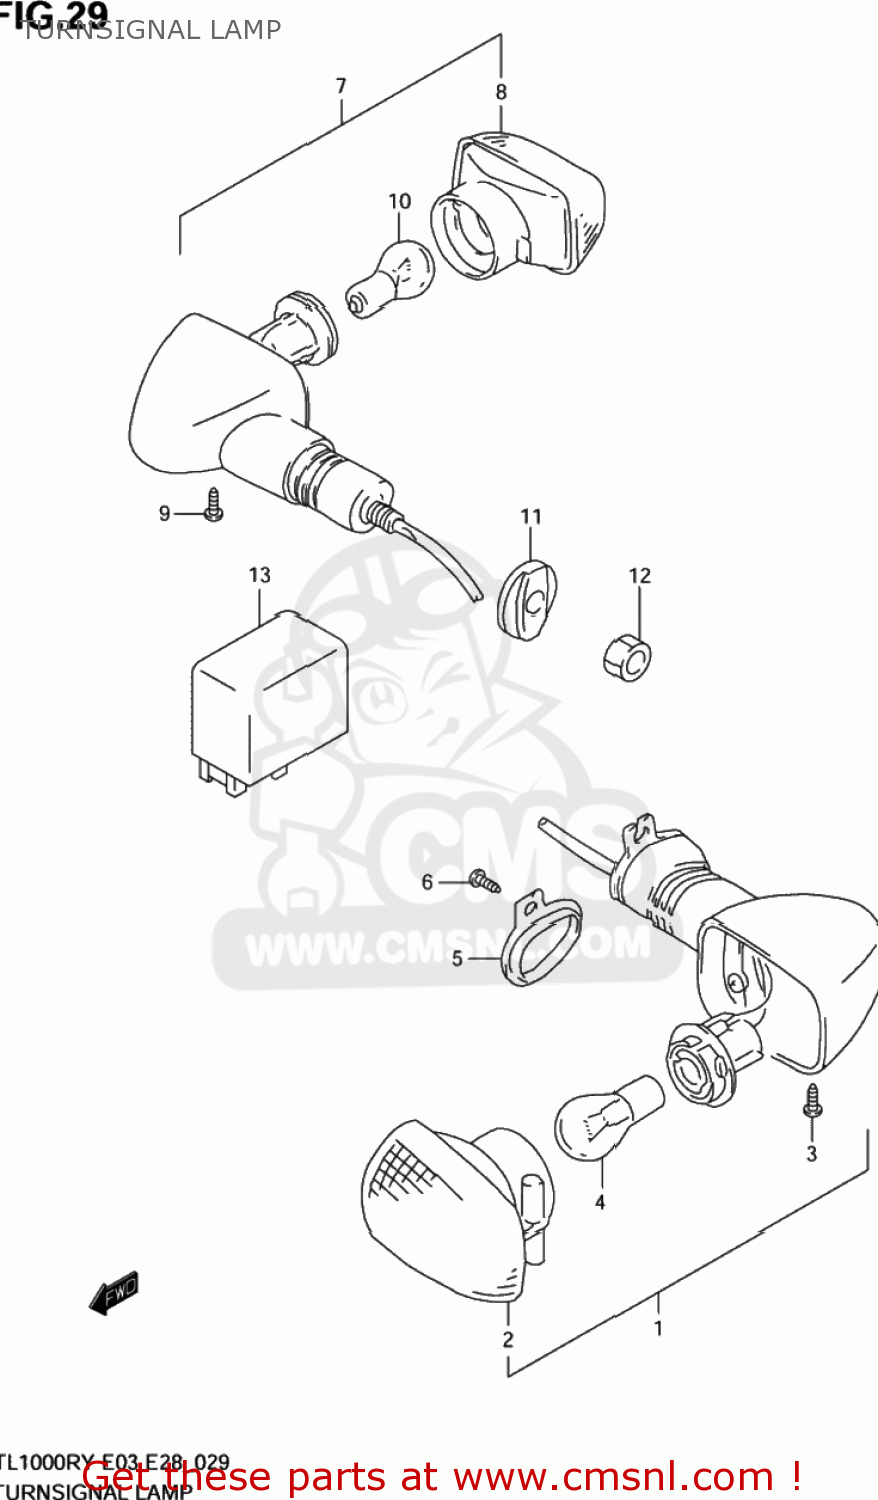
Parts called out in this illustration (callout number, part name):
1	LAMP ASSEMBLY,FRONT TURN SIGNAL
2	LAMP UNIT
3	SCREW
4	BULB(12V21W)
5	PLATE,FR TURNSIGNAL LAMP
6	SCREW
7	LAMP ASSY,RR TURNSIGNAL,R
8	LAMP UNIT
9	SCREW
10	BULB(12V21W)
11	SPACER,RR TURNSIGNAL
12	NUT
13	RELAY ASSY,TURNSIGNAL LAMP
